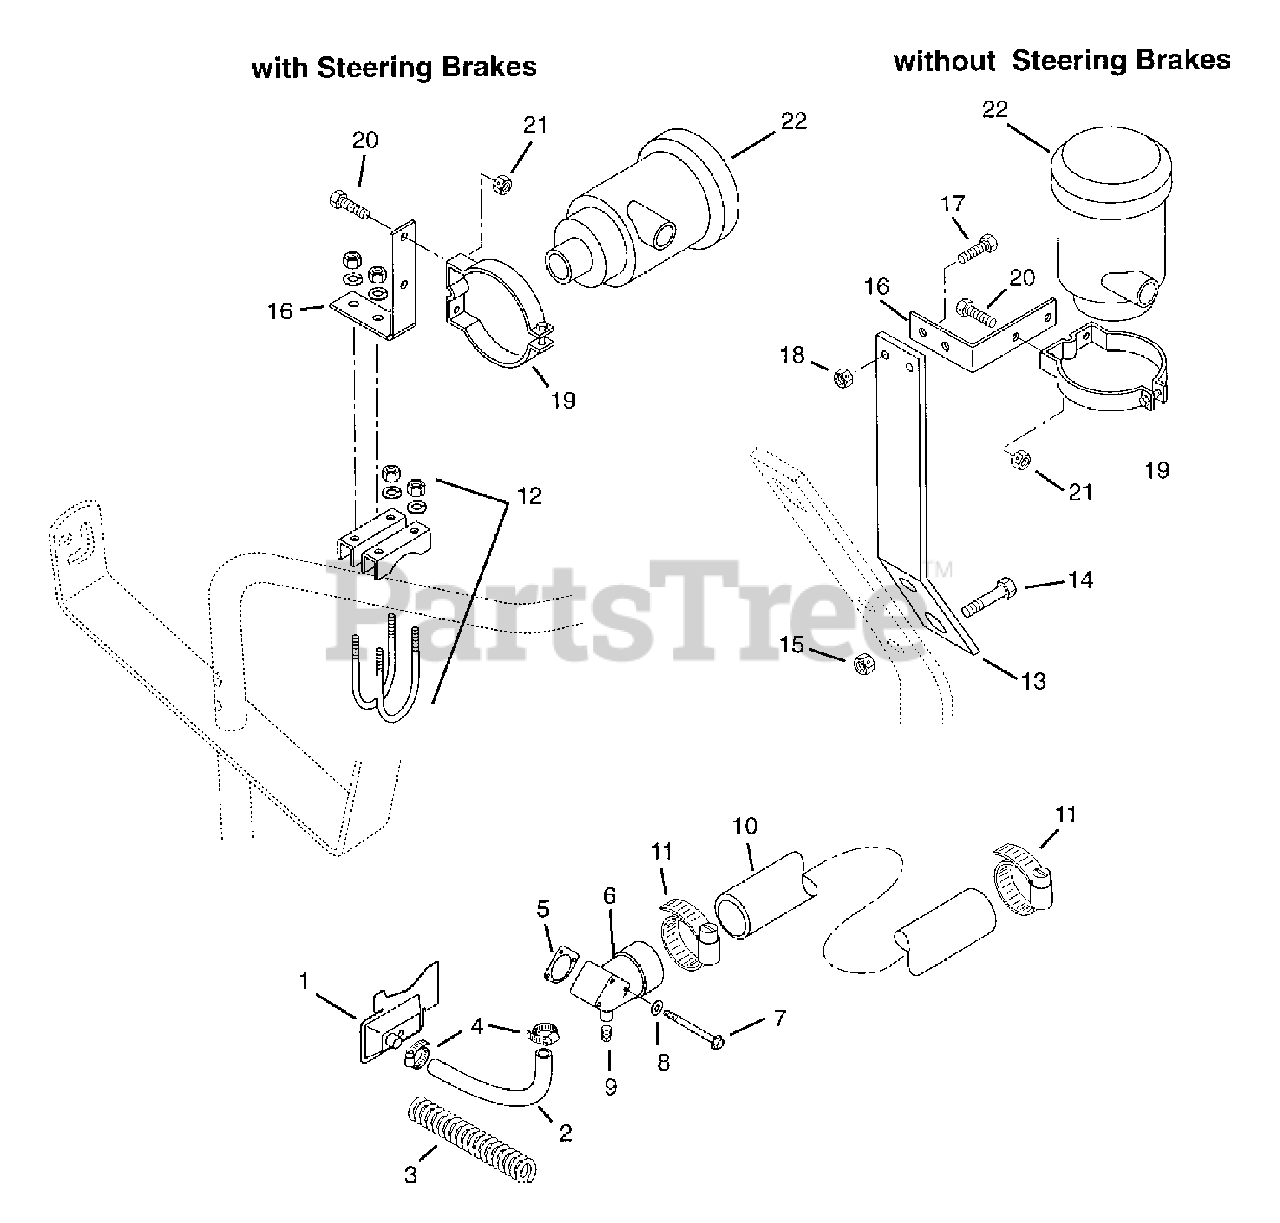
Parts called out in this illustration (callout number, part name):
1	Plate, Breather
2	Hose, Crankcase Vent
3	Spring-Compression .55 x .480 x 6.0
4	Clamp, .88 Diameter Hose
5	Gasket, Air Cleaner Elbow
6	Elbow, Air Cleaner
7	Screw-Machine 8-32 x 2.75 Hex Washer Head
8	Washer-Flat-Steel .219 x .50 x.049
9	Plug, Pipe .12 Square Head UNFIN STL
10	Hose, Air Cleaner
11	Clamp, 2.25 Diameter Hose
12	Clamp, Muffler 1.25
13	Bracket
14	Bolt-Hex .50-13 x 1.50 Grade 5
15	Nut-Locking-Center .50-13
16	Bracket, Air Cleaner Mount
17	Bolt-Hex .38-16 x 1.00 Grade 5
18	Nut-Locking-Center .38-16
19	Bracket, Air Cleaner
20	Bolt-Hex .31-18 x .75 Grade 5
21	Nut-Locking-Center .31-18
22	Air Cleaner
23	Element-Air Cleaner
